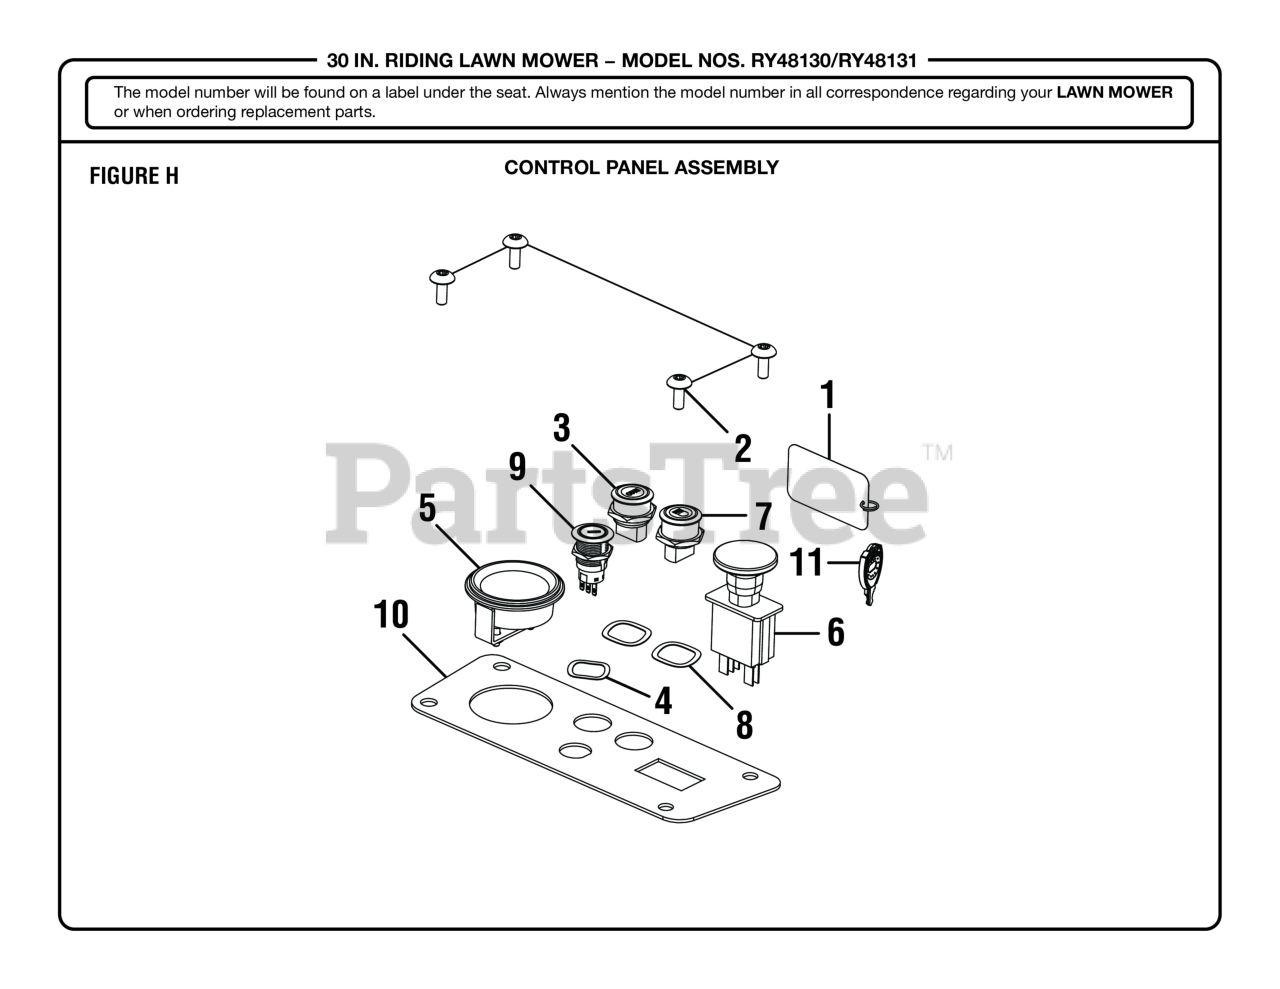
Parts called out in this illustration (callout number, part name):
1	Watch For Kids, Keychain Label
2	Screw (M6 x 10 mm, Soc. Button Hd.)
3	Reverse Mow Operation Button
4	Wavy Washer
5	Gauge Module
6	Power Take Off (PTO) Button
7	Light Switch
8	Wavy Washer
9	Key Module
10	Control Panel Face Plate
